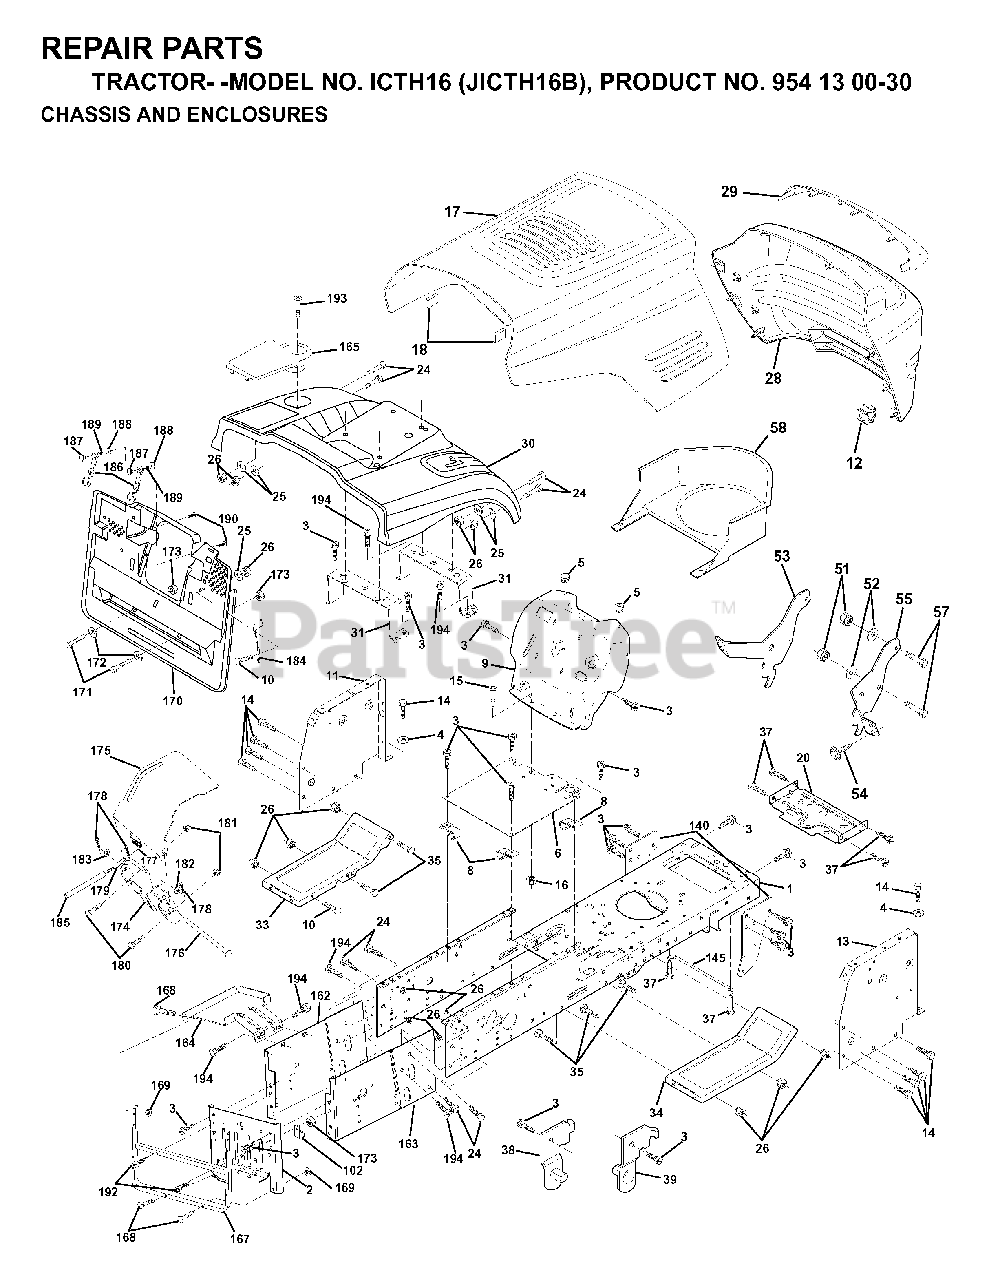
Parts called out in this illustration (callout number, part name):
3	SCREW
5	BUMPER.RUBBER.HOOD
6	SADDLE FLAT
8	CLIP,INSULATOR
10	BOLT D
11	PANEL DASH LH
13	DASH PANEL
16	NUT
18	BUMPER HOOD T
20	PLATE MTG
25	WASHER
26	NUT
31	BRACKET SUPPORT FENDER
38	BRACKET LH PIVOT
39	BRACKET RH PIVOT
51	LOCKNUT
57	BOLT
58	AIR CONDUCTOR
102	CLIP T
140	BRACKET SUSPENSION FRONT
145	ROD PIVOT CHASSIS/HOOD
164	SUPPORT
168	BOLT.ROUND.HEAD.SQUARE.NECK
169	NUT T
170	COVER BACKPLATE
172	WASHER
176	HINGE PIN
177	SPRING COVER LH
178	COTTER PIN
179	ROD PIVOT
180	BOLT RB
181	LOCKNUT
184	BRACKET
185	TUBE LEVER
186	LATCH ASSY
187	WELDNUT
189	LOCKWASHER
190	SCREW
192	SCREW LT
193	SCREW LT
194	SCREW 3/8-16X3/4
